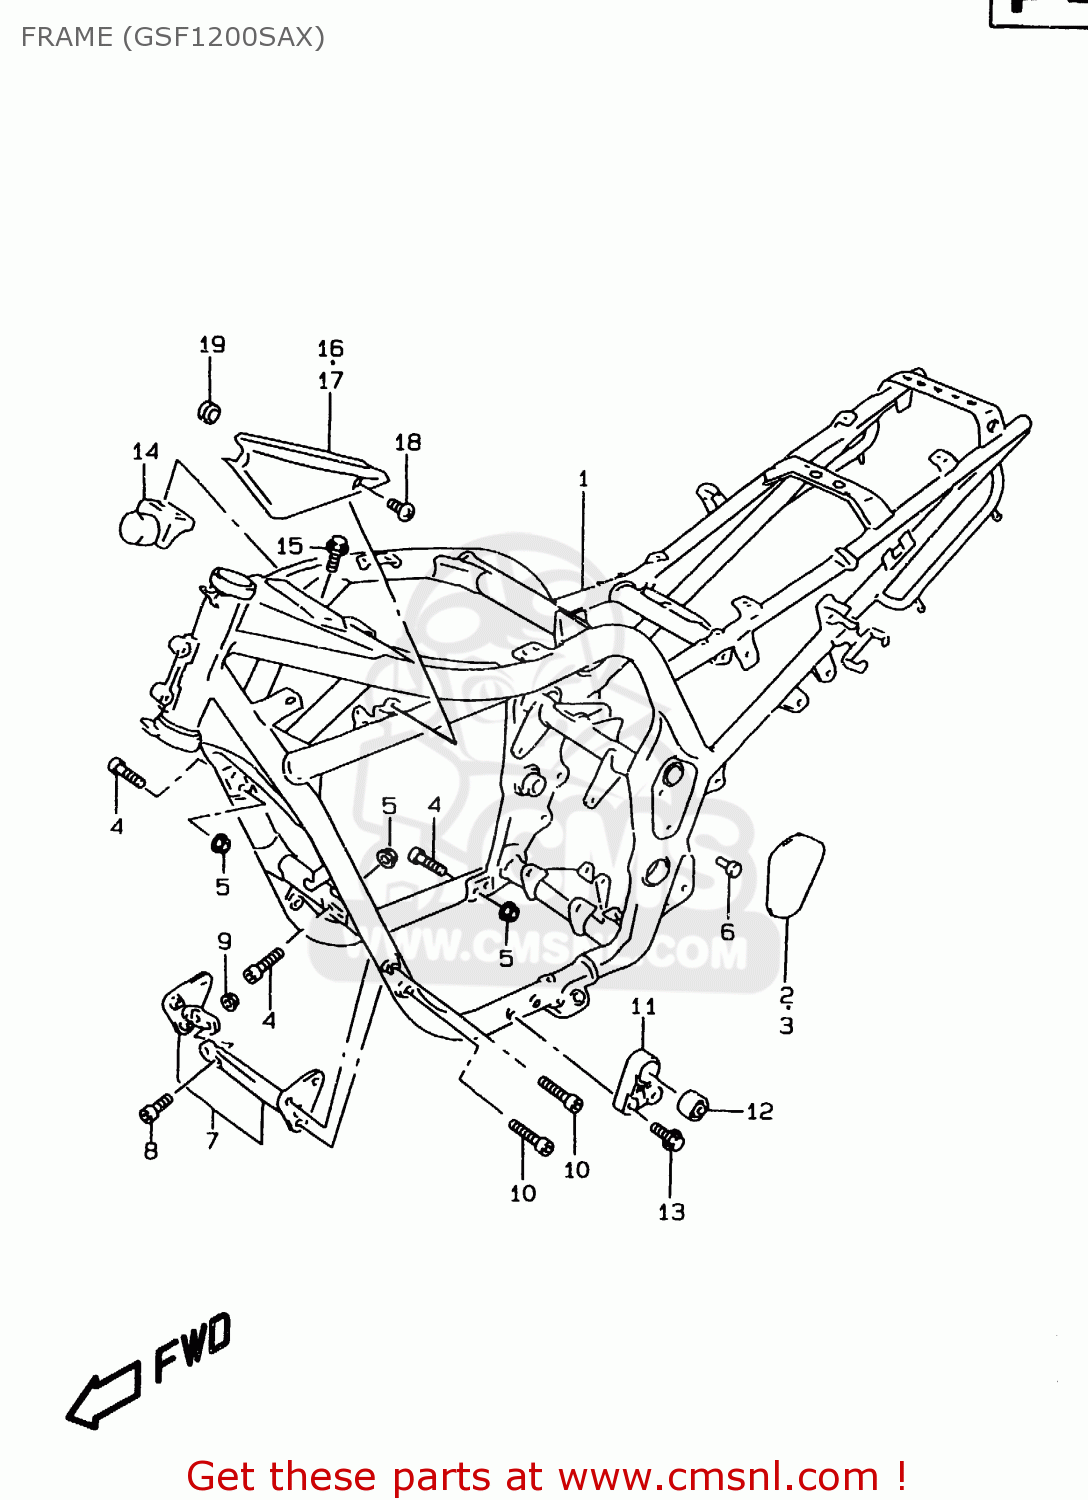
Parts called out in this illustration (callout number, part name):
1	FRAME(BLACK)
2	COVER,FRAME BODY,R
3	COVER,FRAME BODY,L
4	BOLT(10X33)
5	NUT
6	CLIP
7	PLATE ASSEMBLY,ENGINE MOUNT
8	BOLT
9	NUT
10	BOLT
11	BRACKET,ENGINE MOUNTING NO.2
12	BUSH,ENG MOUNTING NO.2
13	BOLT
14	DAMPER COMP,FRAME
15	BOLT
16	COVER,FRAME HEAD,R
17	COVER,FRAME HEAD,L
18	SCREW(5X12)
19	CUSHION
